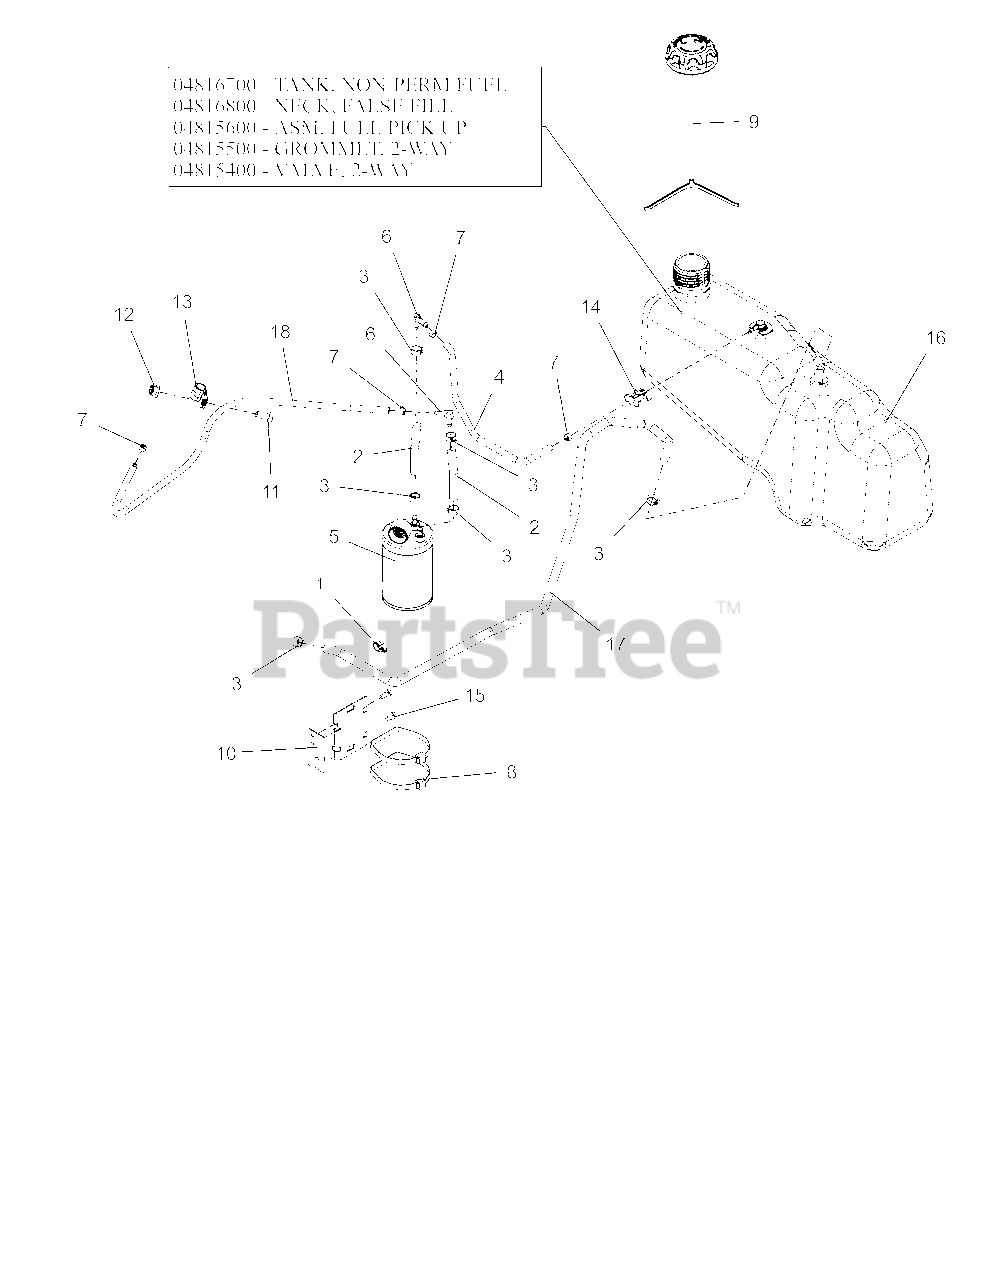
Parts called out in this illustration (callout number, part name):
1	ROUTING CLIP (1/2" ID)
2	HOSE, .25 LOW-PERM BULK GAS
3	CLAMP, FUEL LINE
4	HOSE, .188 LOW-PERM BULK GAS
5	CARBON CANISTER, 300CC
6	FITTING-3/16X1/4 90DEGREE VAC
7	CLAMP-HOSE, SPRING .188
8	P-PLASTIC TIE STRAP LARGE
9	CAP, FUEL VENT-IN 2.25" RATCH.
10	BRKT, CARB CANISTER MOUNT
11	@BLT-HEX .38-16X.75 GR5 YWZC
12	@NUT-LK-NYL-FLG .38-16 YWZC
13	CLAMP, CUSHIONED STEEL
14	CLIP, T, .38-.50
15	SCR-TAP .25-20X.50 HWH TR YWZ
16	ASM,TANK NON-PERM FUEL
16	TANK, ZOOM/ZT NON-PERM, FUEL
16	NECK, FALSE FILL ZOOM/ZT
16	ASM, FUEL PICK-UP ZOOM/ZT 2015
16	GROMMET, 2-WAY
16	VALVE, 2-WAY
17	HOSE, .25 LOW-PERM BULK GAS
18	HOSE, .188 LOW-PERM BULK GAS
